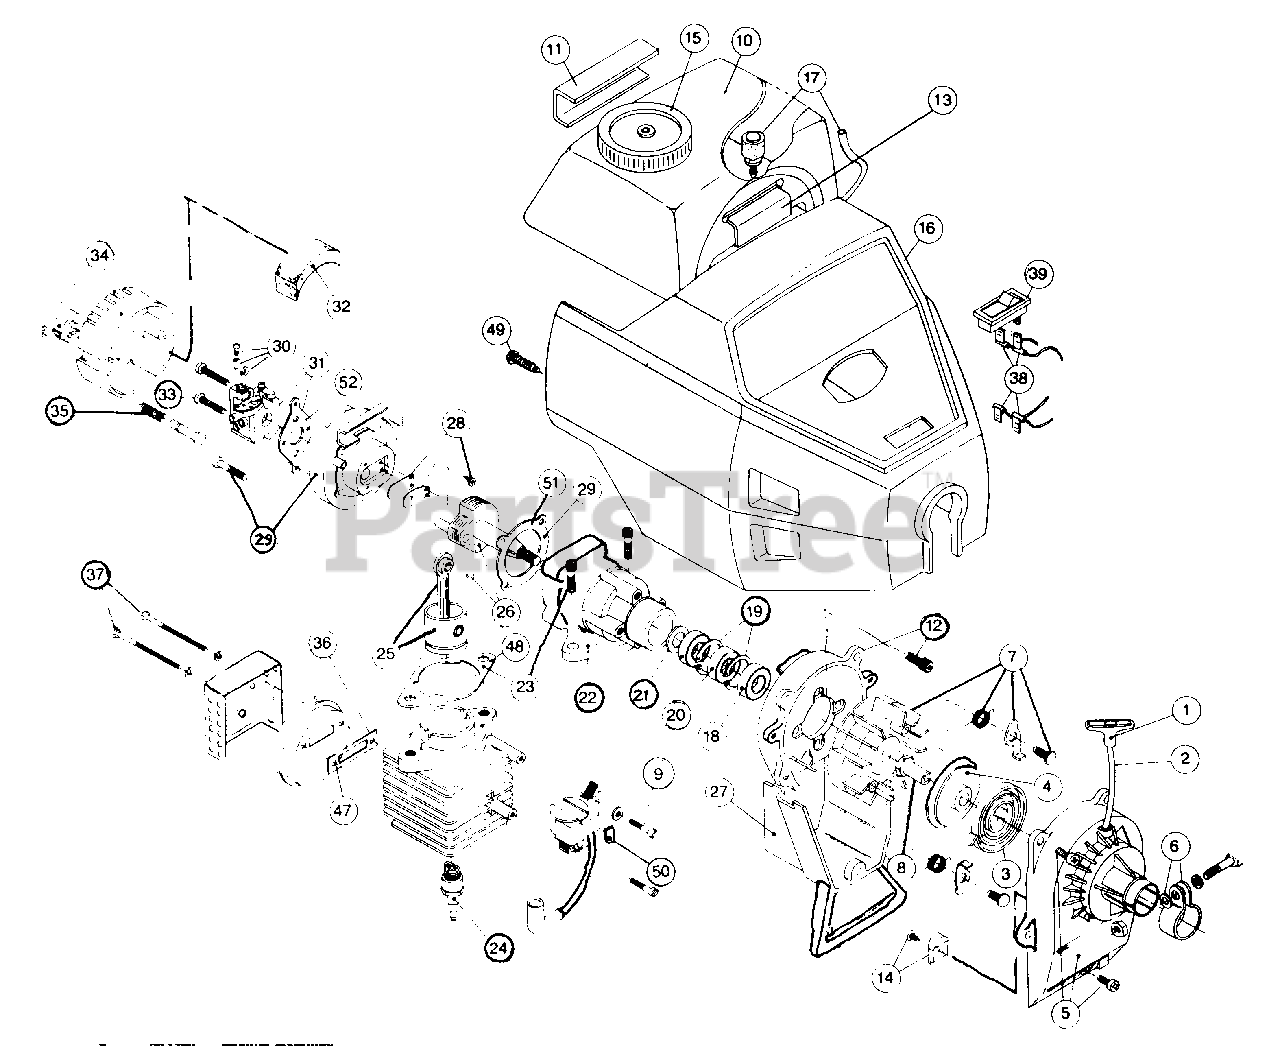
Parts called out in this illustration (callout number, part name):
1	Pull handle
2	Rope
3	Recoil spring
4	Recoil pulley assembly
5	Starter housing assembly
6	Upper clamp assembly
7	Flywheel assembly
8	Square drive nut
9	Module asembly
10	Fuel tank
11	Rear mounting pad
12	Shroud assembly
13	Front mounting pad
14	Pulley retainer assembly
15	Cap and vent assembly
16	Engine cover & decal assembly
17	Fuel line assembly
18	Outer bearing
19	Snap ring assembly
21	Inner bearing assembly
22	Crank case
23	Cylinder assembly
24	Spark plug
25	Piston and rod assembly
26	Power shaft assembly
27	Shroud extension and stand
28	Reed assembly
29	Carburetor mount assembly
30	Throttle adjustment assembly
31	Carburetor assembly
32	Air cleaner filter
33	Carburetor mounting screw assembly
34	Air cleaner cover assembly
35	Choke knob assembly
36	Muffler assembly
37	Muffler mounting bolt assembly
38	Wire bad assembly
39	Switch assembly
47	Exhaust gasket (10 pack)
48	Cylinder gasket (10 pack)
49	Engine cover mounting screw assembly
50	Ground lab
51	Carburetor mount gasket (10 pack)
52	Carburetor gasket (10 pack)
